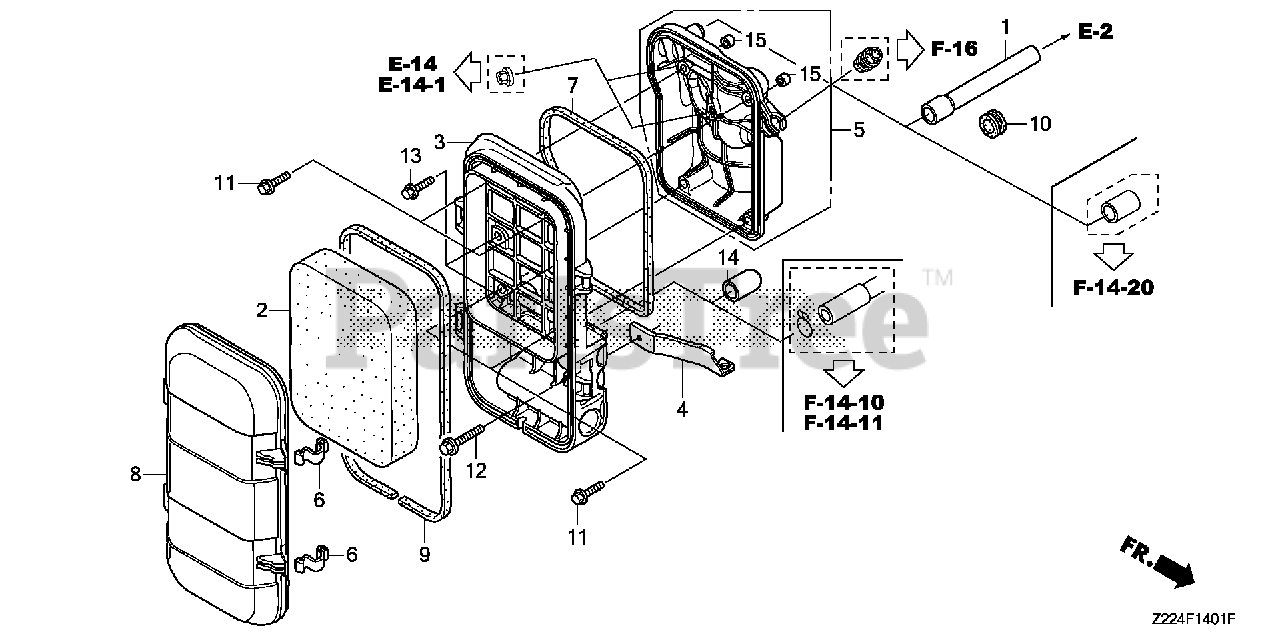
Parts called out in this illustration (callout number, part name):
1	TUBE, BREATHER
2	ELEMENT, AIR CLEANER
3	HOUSING, AIR CLEANER
4	STAY, AIR CLEANER
5	BASE, AIR CLEANER
6	SPRING, AIR CLEANER HOUSING LID
7	SEAL, AIR CLEANER HOUSING
8	COVER, AIR CLEANER
9	SEAL, AIR CLEANER COVER
10	GROMMET, FENDER
11	BOLT, FLANGE (5X18)
12	BOLT, FLANGE (6X32)
